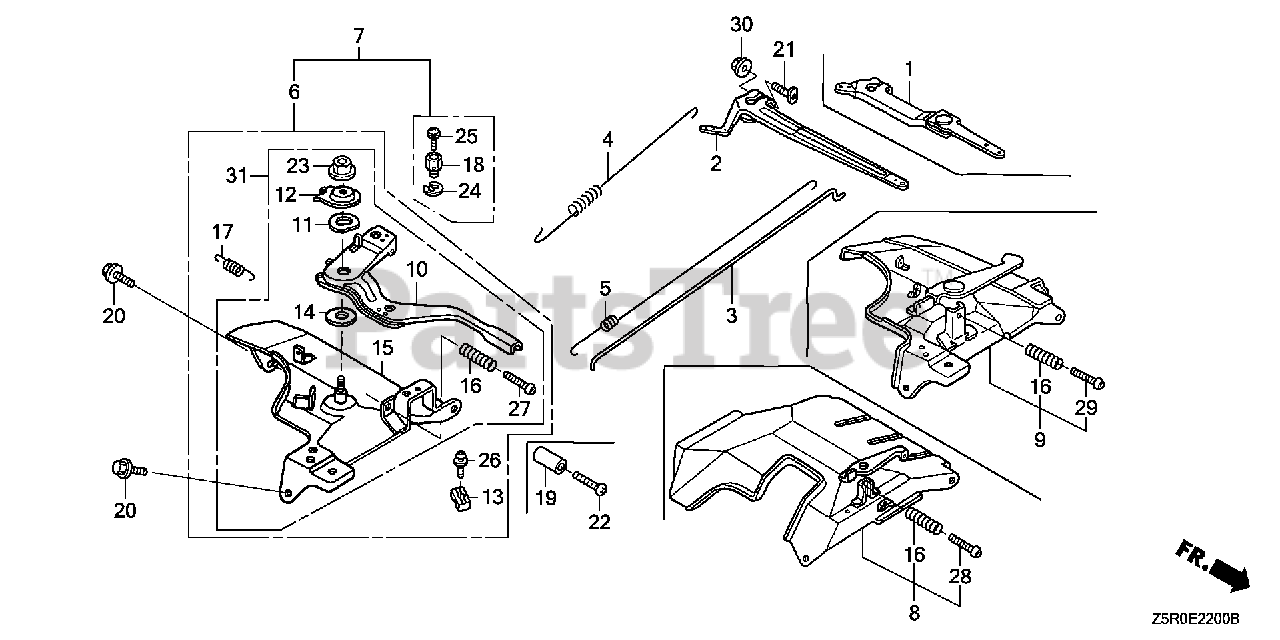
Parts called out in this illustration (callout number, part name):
1	ARM, GOVERNOR
3	ROD, GOVERNOR
4	SPRING, GOVERNOR
5	SPRING, THROTTLE RETURN
8	CONTROL ASSY. (COO)(FOR U.S.A.)
8	CONTROL ASSY.
16	SPRING, CONTROL ADJUSTING Use from Engine SN 2327377.
20	BOLT, FLANGE (6X12) (CT200)
21	BOLT, GOVERNOR ARM
28	SCREW, PAN (5X35)
30	NUT, FLANGE (6MM)
